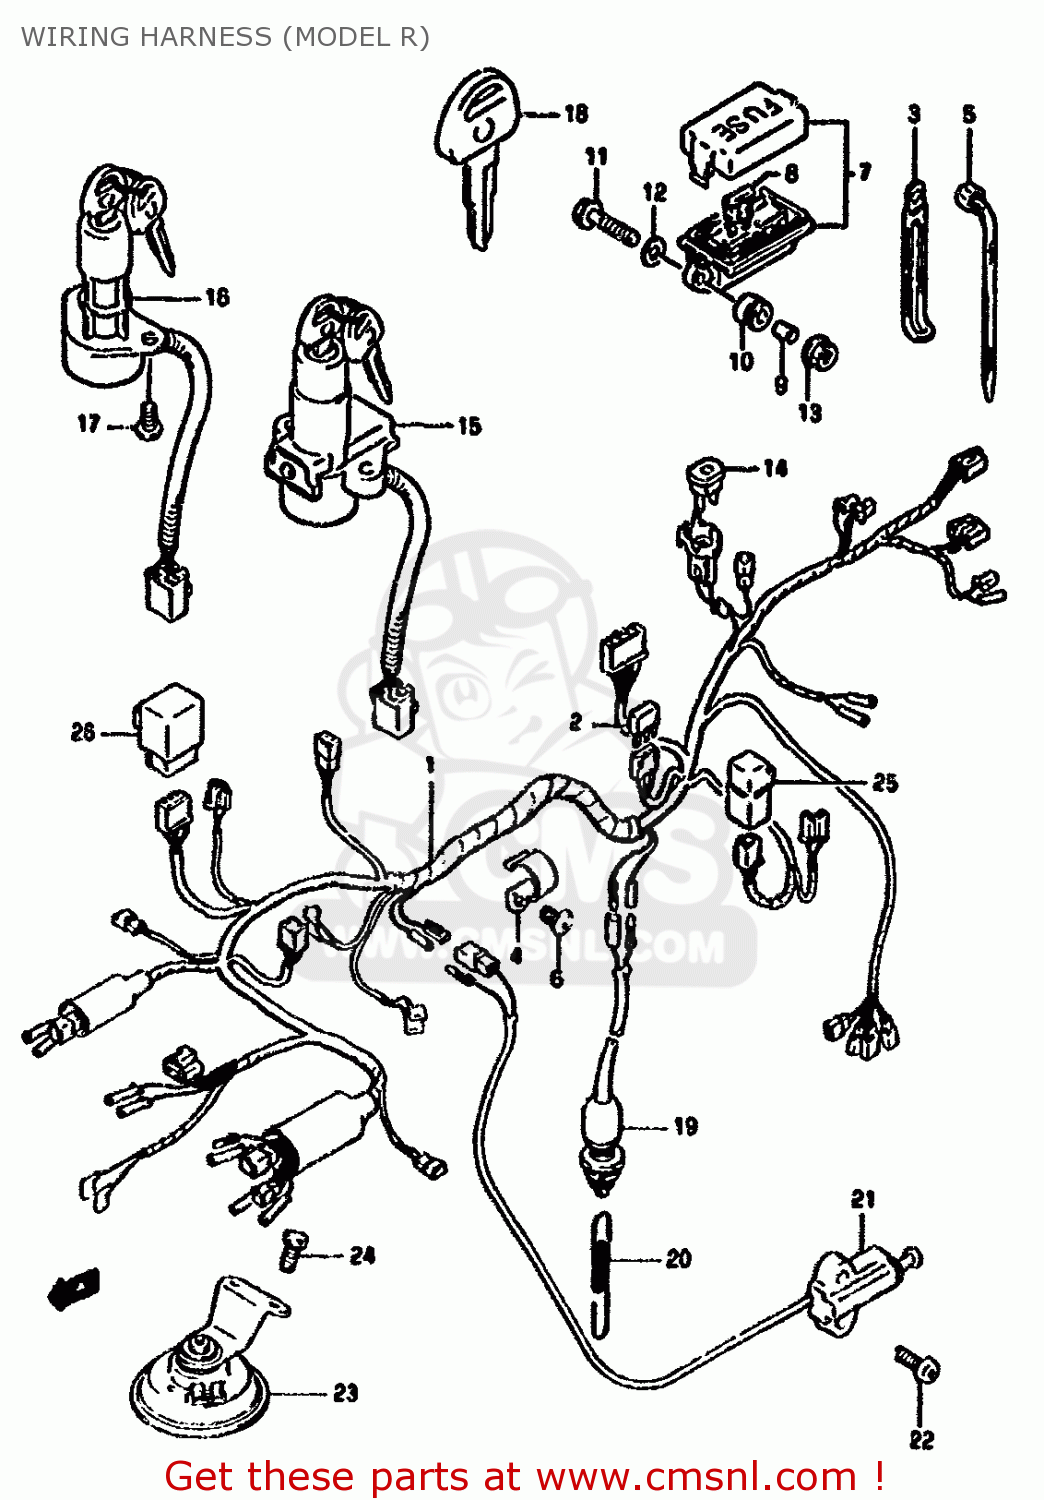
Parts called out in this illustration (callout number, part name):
1	HARNESS,WIRING
2	DIODE(STANLEY DE8804)
3	CLAMP
4	CLAMP
5	CLAMP(L:125)
6	SCREW
7	BOX ASSY,FUSE
8	FUSE(10A)
9	SPACER
10	CUSHION 8X18X17.5
11	BOLT
12	WASHER(6.5X18X1)
13	NUT
14	BREAKER ASSY,CIRCUT
15	LOCK ASSY,STEERING
16	SWITCH ASSY,IGNITION
16B	BOLT
16C	WASHER,LOCK
17	SCREW 6X12
18	KEY,BLANK
19	KEY,BLANK
20	SPRING
21	SPRING
22	SWITCH ASSEMBLY,SIDE STAND
23	SCREW
24	BOLT
25	HORN ASSEMBLY
26	BOLT
27	WASHER,LOCK
28	RELAY ASSEMBLY
29	RELAY ASSY,MOTOR CONTROL
